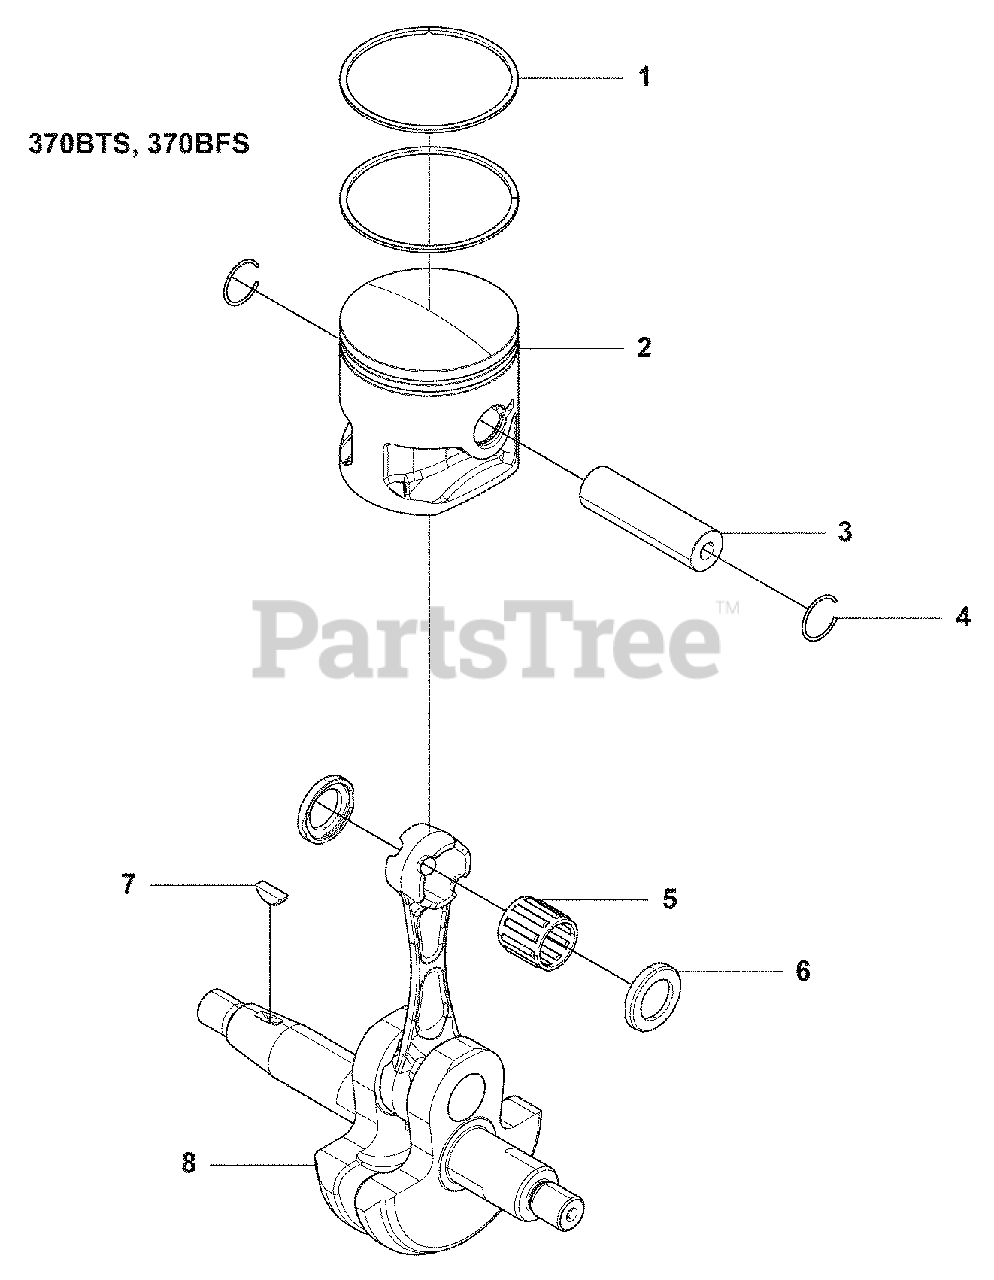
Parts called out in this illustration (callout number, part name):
4	Snap Ring
5	Bearing
6	Washer
7	Flywheel Key
8	Shaft, Comp
